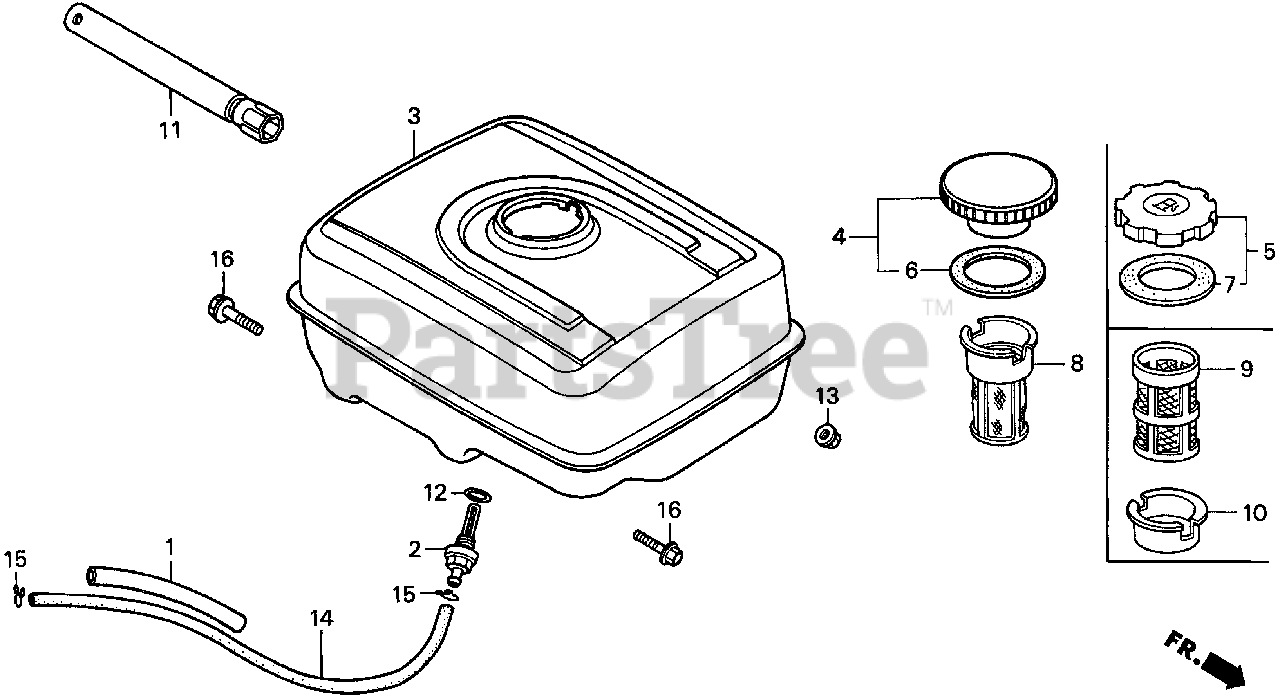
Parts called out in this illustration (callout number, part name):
1	RUBBER, SUPPORTER
1	RUBBER, SUPPORTER (107MM)
2	JOINT, FUEL TANK
3	TANK, FUEL *NH31* (MCKINLEY WHITE)
4	CAP, FUEL FILLER
5	CAP, FUEL FILLER
6	GASKET, FUEL FILLER CAP
7	GASKET, FUEL FILLER CAP
12	O-RING (13.5X1.5) (ARAI)
13	NUT, FLANGE (8MM)
14	BULK HOSE, FUEL (4.5X3000) (4.5X235)
15	CLIP, TUBE (B8)
16	BOLT, FLANGE (8X25)
